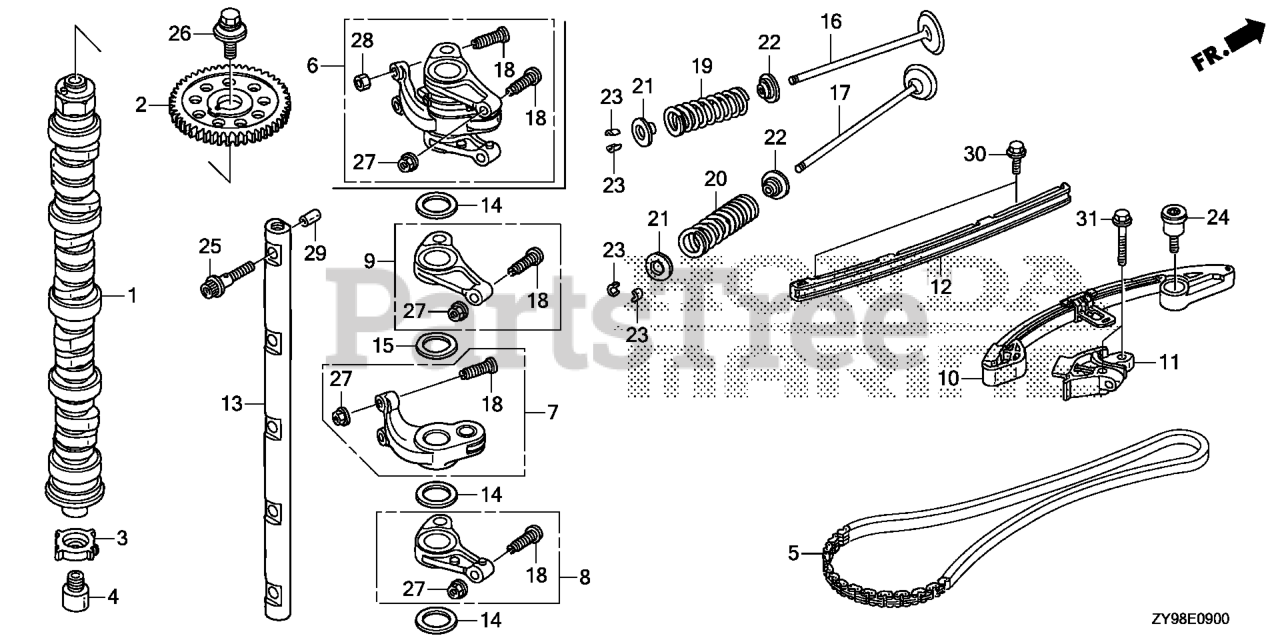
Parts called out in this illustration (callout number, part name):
2	SPROCKET, CAM CHAIN DRIVEN (46T)
3	PLATE, TDC PULSER
4	BOLT, TDC PULSER PLATE
5	CHAIN (132L)
6	ARM ASSY., ROCKER
10	TENSIONER, CAM CHAIN
11	SLIDER, CAM CHAIN TENSIONER
12	GUIDE, CAM CHAIN
13	SHAFT, ROCKER ARM
16	VALVE, IN.
17	VALVE, EX.
18	SCREW, TAPPET ADJUSTING
19	SPRING, IN. VALVE
20	SPRING, EX. VALVE
21	RETAINER, VALVE SPRING
22	SEAT, VALVE SPRING
23	COTTER, VALVE (FUJI VALVE)
24	BOLT, TENSIONER PIVOT
25	BOLT, ROCKER ARM SHAFT
26	BOLT-WASHER (10X30)
27	NUT, TAPPET ADJUSTING (TOKAI TRW)
28	NUT, TAPPET ADJUSTING
29	PIN A, DOWEL (7X12)
30	BOLT, FLANGE (6X14)
31	BOLT, FLANGE (6X28)
